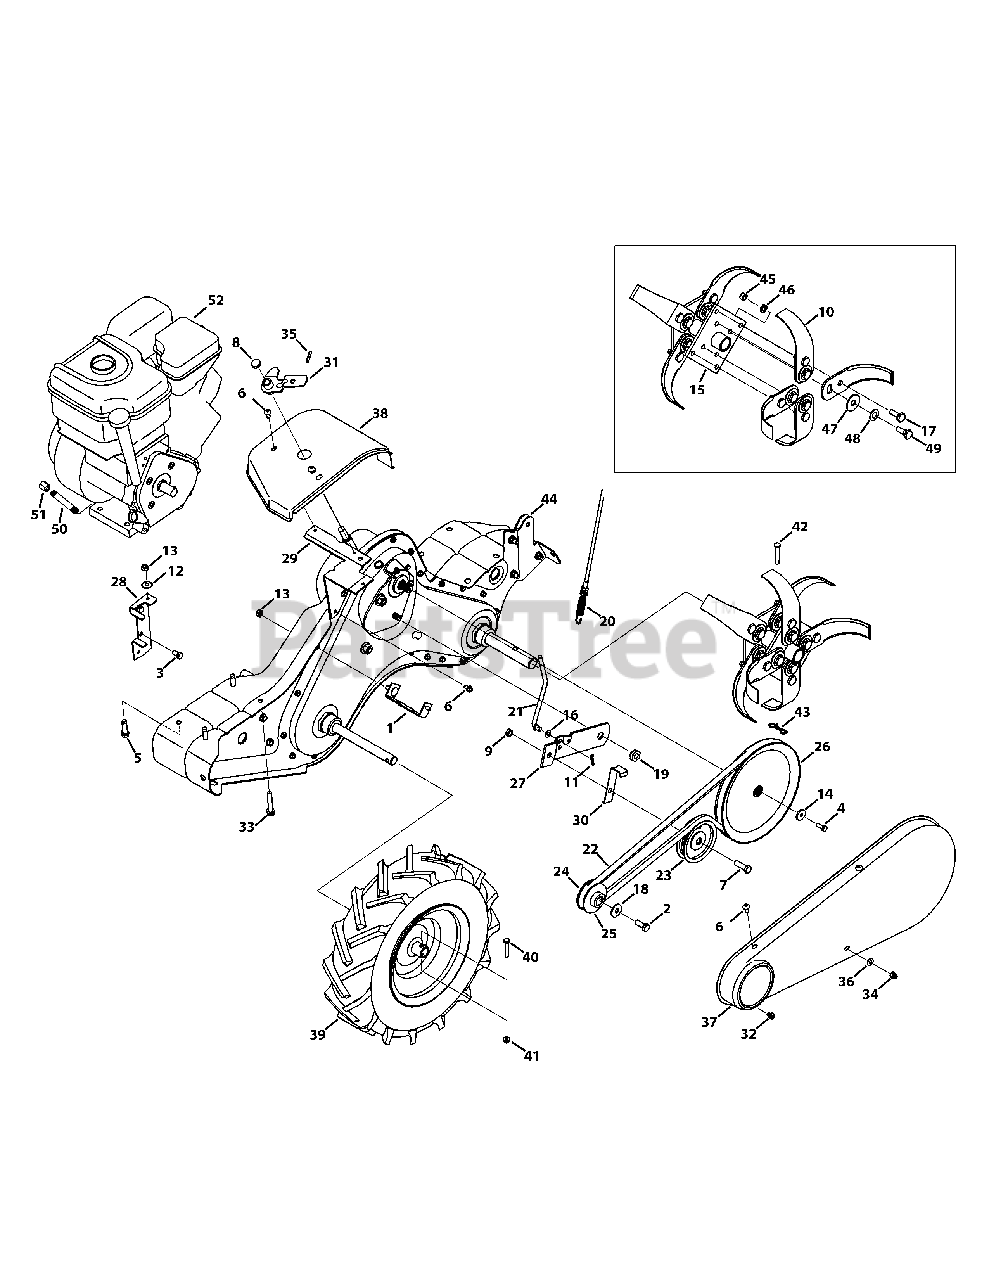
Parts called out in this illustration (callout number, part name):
1	Belt Cover Bracket Assembly
2	Hex Screw, 3/8-24 x 1.00
3	Hex Lock Screw, 5/16-24 x .625
4	Hex Lock Screw, 1/4-28 x .625
5	Screw, 3/8-16 x 1.250
6	Hex Washer Screw, 1/4-20 x .625
7	Hex Head Screw, 3/8-16 x 1.25
9	Jam Lock Nut, 3/8-16
10	Articulating Tine
11	Cotter Pin, .072 DIA. x 1.13 LG
12	Bell Washer, .340 x .872 x .060
13	Hex Nut, 5/16-18
14	Washer, Flat, .265 x .938 x .120
15	Tine Adaptor Assembly
15	Tine Assembly
16	Washer, Spring, .317 x .625 x .020
17	Shoulder Screw, 3/8-24 x 1/2 x .180
18	Washer, Bell, .396 x 1.140 x .095
19	Shoulder Nut, 7/16-20
20	Clutch Cable
21	Idler Pulley Rod
22	Belt, 4L x 58.16 LG
23	Flat Idler Pulley w/ Flanges, 3.75 O.D.
24	Engine Pulley, Inner Half
25	Engine Pulley, Outer Half
26	Input Pulley, 4L x 8.594
27	Idler Pulley Bracket
28	Belt Keeper Bracket
29	Shift Cover Bracket
30	Idler Belt Keeper
31	Shift Crank Assembly
32	Screw, 1/4-20:0.375
33	Hex Head Screw, 5/16-18 x 1.50
34	Lock Nut ,Cap, 1/4-28
35	Spiral Pin, 3/16 x 1.00
36	Washer, Flat, .271 x .630 x .065
37	Belt Cover
38	Shift Cover
39	Wheel, 16 x 4.6 x 8
40	Hex Screw, 1/4-20 x 1.50
41	Flange Lock Nut, 1/4-20
42	Clevis Pin, .375 x 1.75
43	Cotter Pin, Bow Tie
44	Complete Gear Case Assembly
45	Hex Lock Nut, 3/8-24
46	Washer, Lock, 3/8
47	Washer, Flat, .51 x 1.5 x 0.07
48	Washer, Bell, .525 x 1.00 x .050
49	Screw, Shoulder, 3/8-24 x 1/2 x .325
50	Straight Pipe, 1/4 x 3.5
51	End Cap, 1/4
52	Engine - BS-12T102-0937-F8
